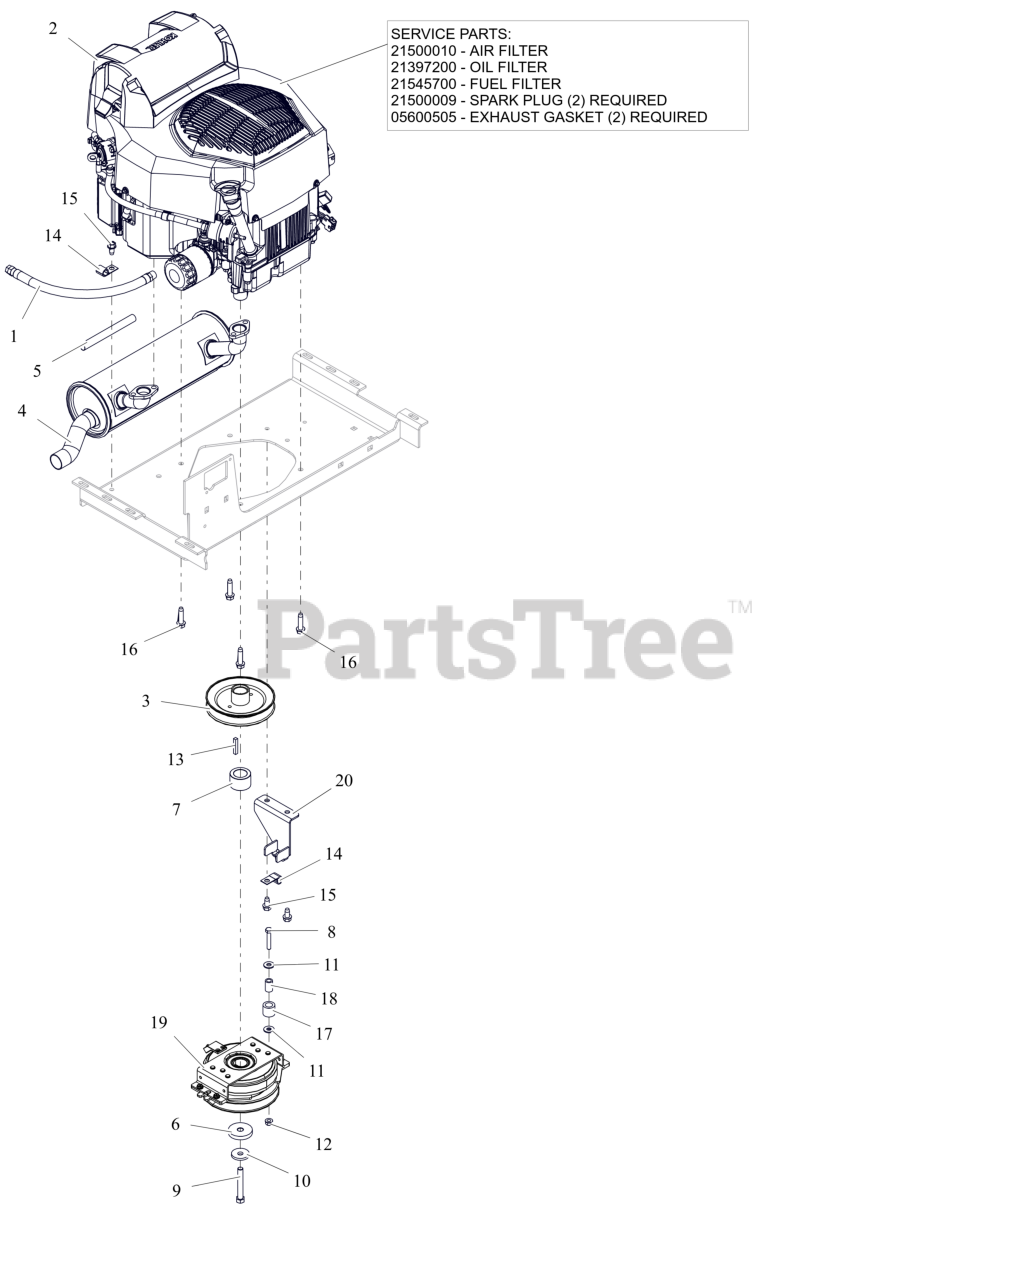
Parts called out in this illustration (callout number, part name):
1	HOSE, OIL DRAIN
2	ENGINE, KOHLER ZT740 CONFIDANT
2	AIR CLEANER, KOHLER CONFIDANT
2	FILTER, OIL - KOH CV20
2	FILTER-FUEL KOHLER COURAGE PRO
2	PLUG, SPARK KOHLER
2	GASKET, MUFFLER KOHLER TWIN
3	WLDMT, TRANSAXLE DRIVE PULLEY
4	MUFFLER, ZT730/ZT740
5	SLEEVE, THERMAL 6"
6	SPACER, .474/.459X2.00X.350
7	SPCR, 1.125 x 1.750 x 1.147
8	BLT, HEX .31-18X1.75 G5 ZCC
9	BLT, HEX 0.4375-20X3 G8 ZCC NT
10	WASHER, 7/16" SPRING DISK
11	WSHR,FLT .375X.875X.083 ZCC
12	NUT,LK-CTR-FLG .31-18 GF ZCC
13	KEY-SQ .25 X 1.50 X .25 SAE
15	SCR,TAP .375-16X.75 HWH TR ZCC
16	SCR-TAP .38-16X1.50 HWH ZCC
17	BUMPER,RUBBER .62X1.0X.88 LG
18	BUSH.,S.391X.622X.950 ST
19	CLUTCH- OGURA GT2.75-DC03(D)
20	BRKT- CLUTCH STOP - BLACK
